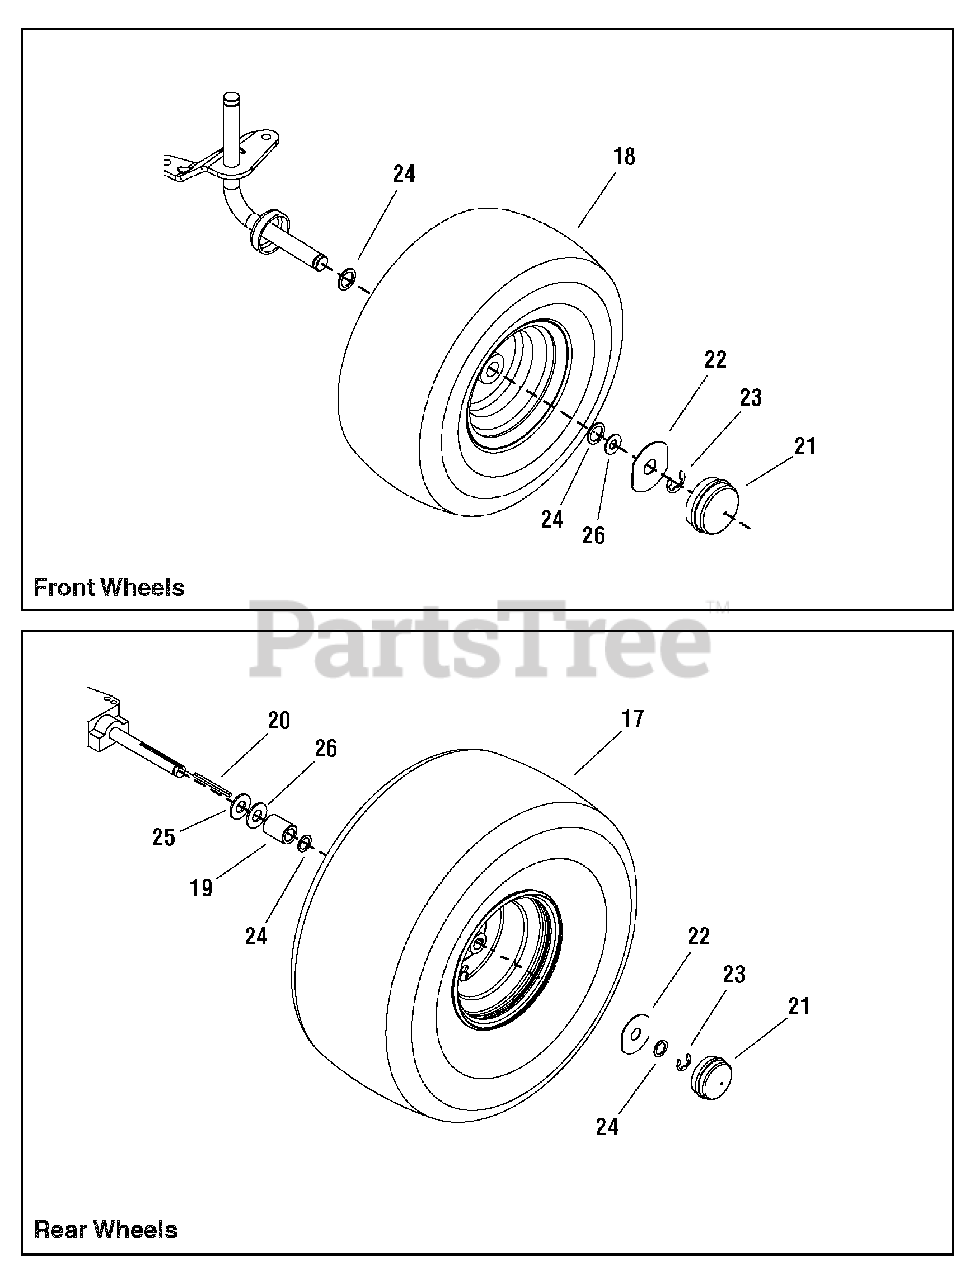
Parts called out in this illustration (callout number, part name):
17	WHEEL & TIRE ASSEMBLY, Rear, 22 x 10 - 8
18	WHEEL & TIRE ASSEMBLY, Front, 14.4 x 6
19	SPACER, Axle, Rear PM Hunter
20	KEY, Parallel
21	HUB CAP, 2.361 D, Grey Poly 1.3H, VIPER
22	WASHER, Special, 2-1/2
23	RING, Klipring, EXT For .75 Dia Shaft blk
24	WASHER, 3/4
25	WASHER, 3/4
